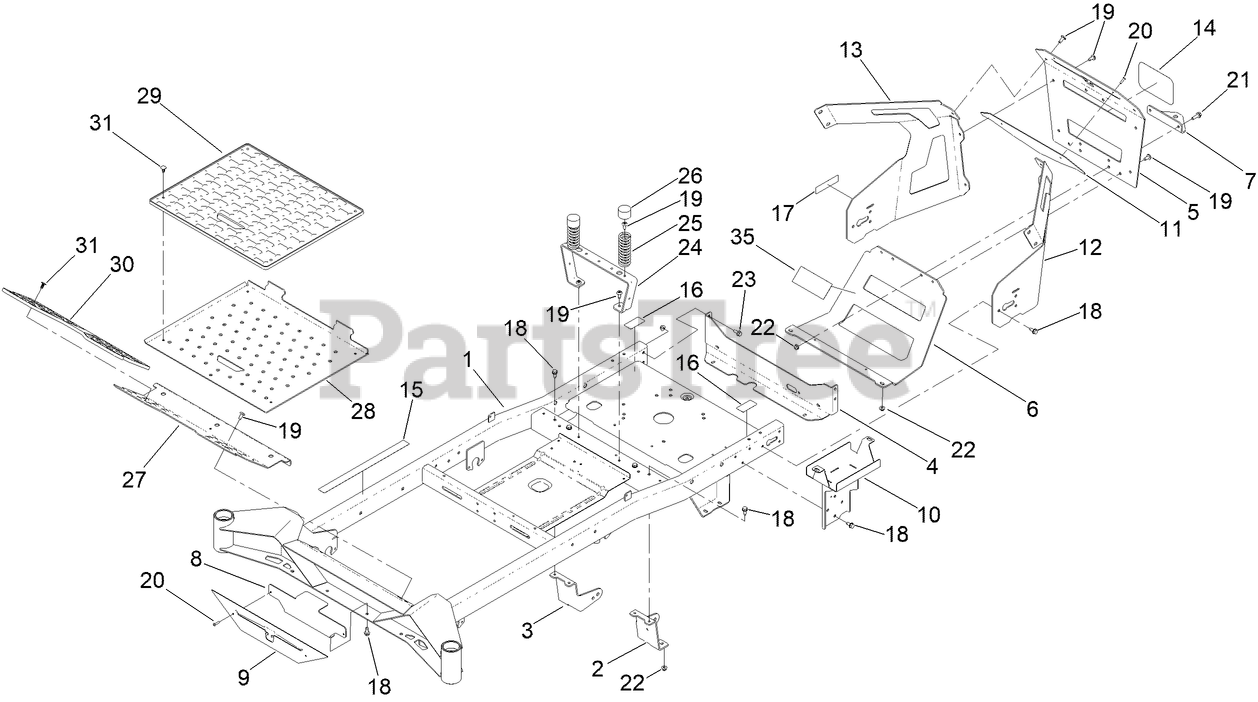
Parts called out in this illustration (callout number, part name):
1	SERVICE ASM-FRAME, TITAN
2	MOUNT-DRIVE, LH
3	MOUNT-DRIVE, RH
4	PLATE-MOUNT
5	GUARD-ENGINE
6	GUARD-MUFFLER
7	BRACKET-HITCH
8	PLATE-BACKER
9	LOGO-PLATE-FRONT
10	WA-BATTERY MOUNT
11	PLATE-BACKER
12	GUARD-ENGINE LH
13	GUARD-ENGINE-RH
14	DECAL
15	DECAL-WARNING
16	DECAL-BYPASS
17	DECAL-SPARK ARRESTER
18	SCREW-HWHTF
20	RIVET-TRIFOLD
21	SCREW-HHF
22	NUT-HF
23	SCREW-HHF
24	SUPPORT-SEAT
25	SPRING-COMPRESSION
26	CAP-PROTECTOR
27	PAN-FLOOR
28	PAN-FLOOR
29	FLOOR MAT
30	FLOOR MAT - TITAN
31	PLUG-PLASTIC
35	TAPE-HEAT
